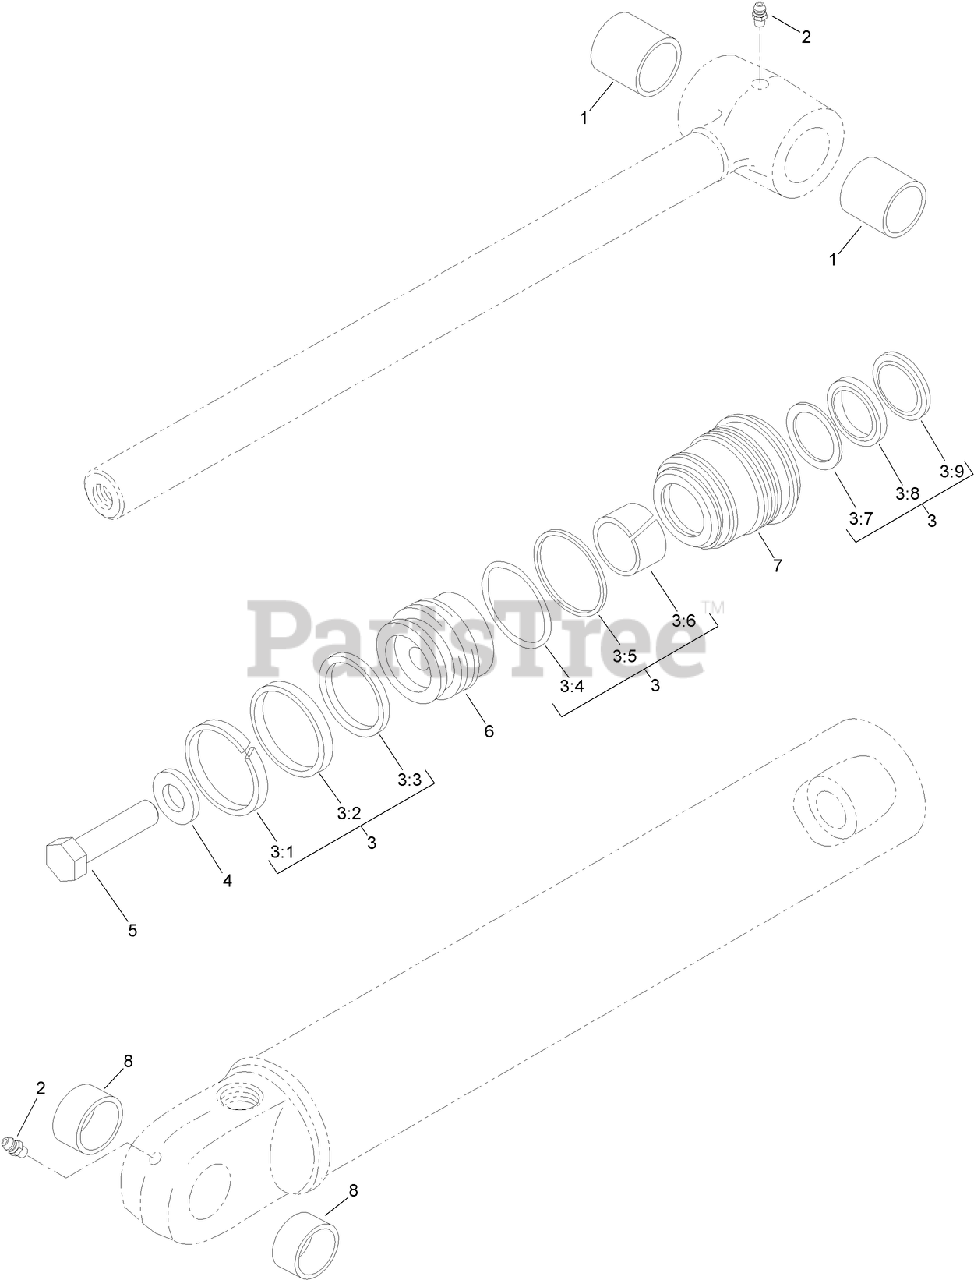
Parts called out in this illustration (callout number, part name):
1	BUSHING
2	FITTING-GREASE
3	SEAL KIT
3:1	RING-WEAR
3:2	Seal-Piston
3:3	Ring-Seal
3:4	O-RING
3:5	Ring-Back-Up
3:6	BUSHING-CENTER
3:7	SEAL-BUFFER
3:8	Cup-U
3:9	WIPER
4	Washer
5	Screw-HH
8	BUSHING
